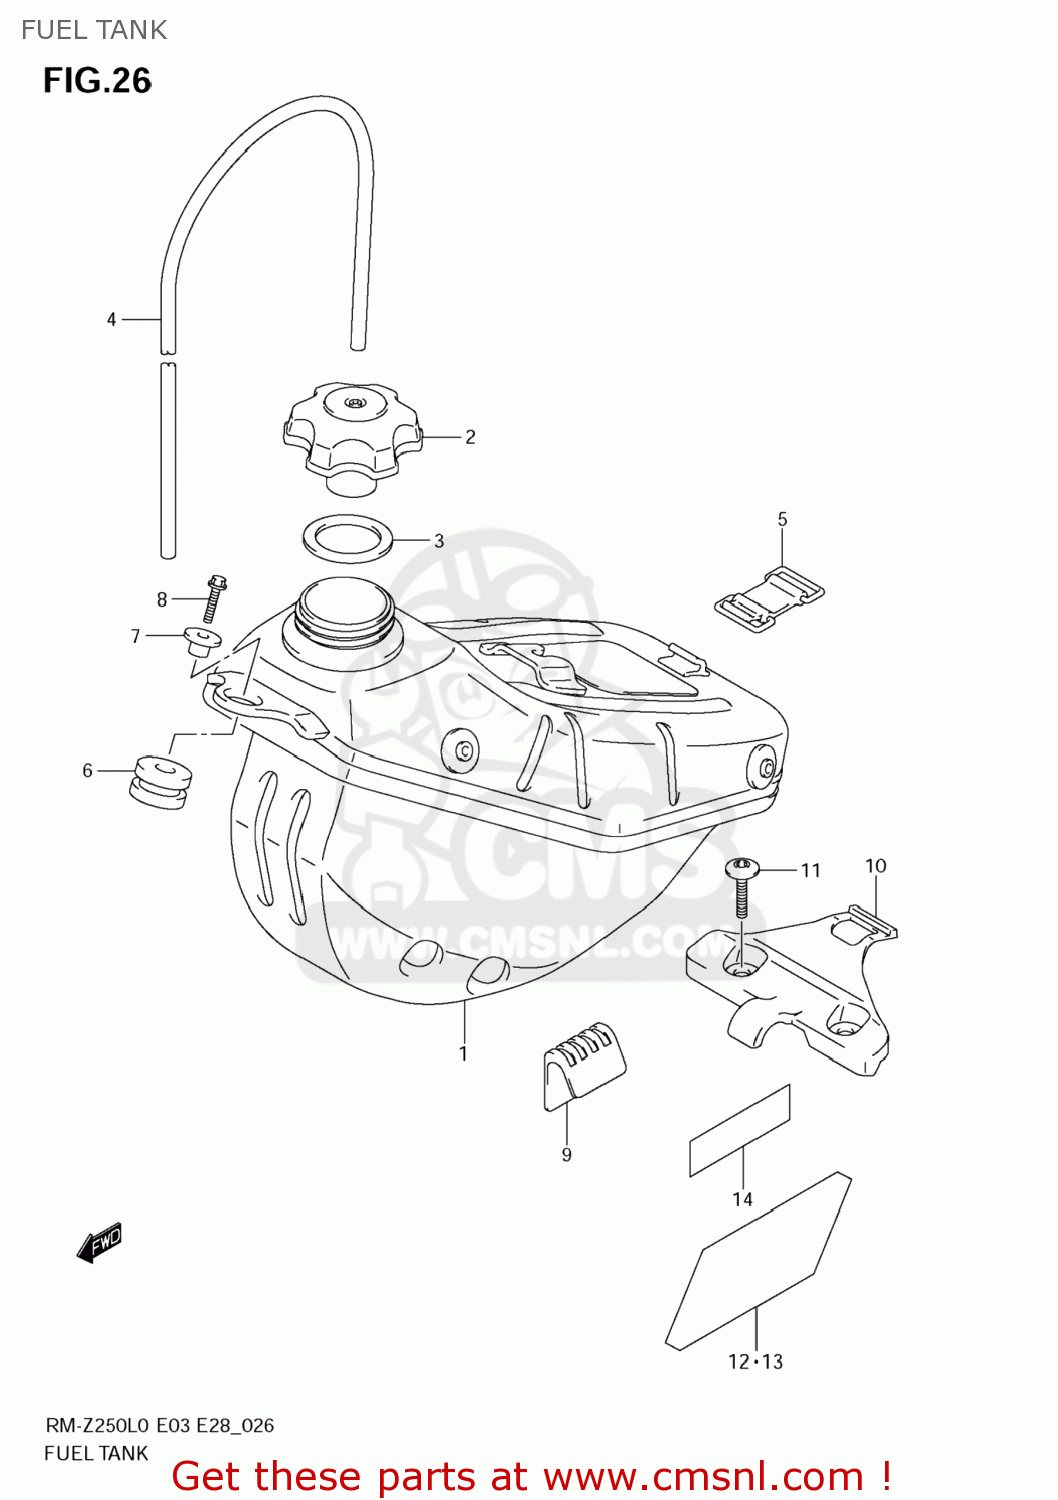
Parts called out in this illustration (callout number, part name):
1	TANK,FUEL
2	CAP,FUEL TANK FILLER
3	GASKET,CAP (NAS)
4	HOSE(5X8.2X600)
5	BAND,FUEL TANK RR
6	CUSHION,FUEL TANK FR
7	SPACER
8	BOLT(6X30)
9	CUSHION,FUEL TANK SIDE
10	CUSHION,FUEL TANK RR
11	SCREW(6X26.5)
12	PROTECTOR,RADIATOR,R
13	PROTECTOR,RADIATOR,L
14	PROTECTOR,RADIATOR
